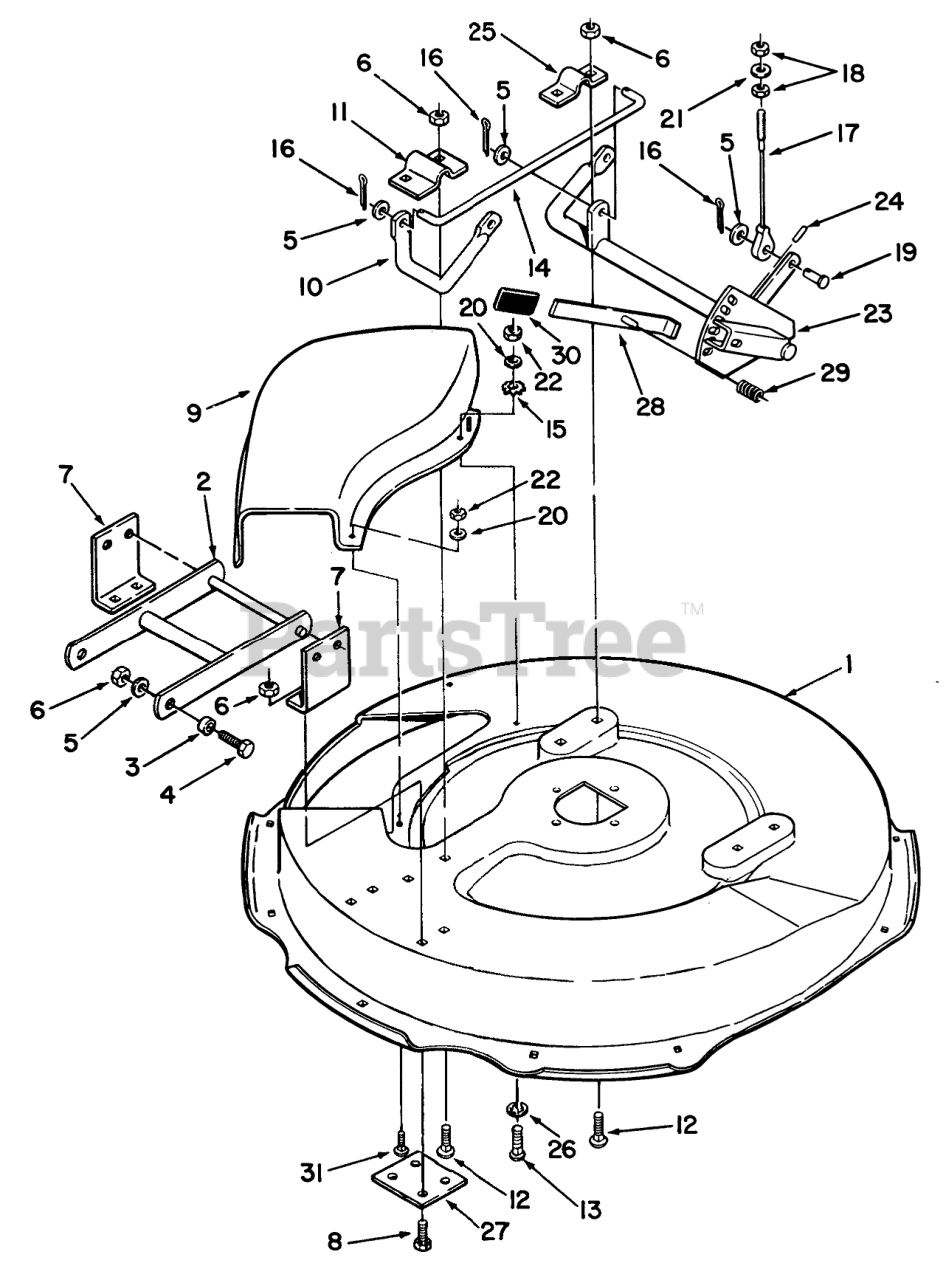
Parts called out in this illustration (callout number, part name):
1	DECK 30" MOWER R
2	ASSY MWR FRONT MO R
3	SPACER
4	SCREW-HH
5	WASHER-FLAT
6	NUT-LOCK, NI
7	BRKT FRONT MOWER R
8	SCREW-HH
9	Deflector-Mower
10	ROD HEIGHT ADJ R
11	CLAMP B
12	BOLT-CARR
13	SCREW-CARR
14	ROD HEIGHT ADJUST
15	WASHER-LOCK/EXT
16	PIN-COTTER
17	CABLE MOWER SUPPORT
18	NUT-HEX
19	CLEVIS PIN
20	WASHER-FLAT
21	WASHER-PLAIN
22	NUT-LOCK, NI
23	HEIGHT ADJ ASSY R
24	SPIROL PIN
26	WASHER-LOCK, INTERNAL
27	PLATE-BACKUP R
28	LEVER ASSY
29	SPRING-COMPRESSION
31	SCREW-CARRIAGE
